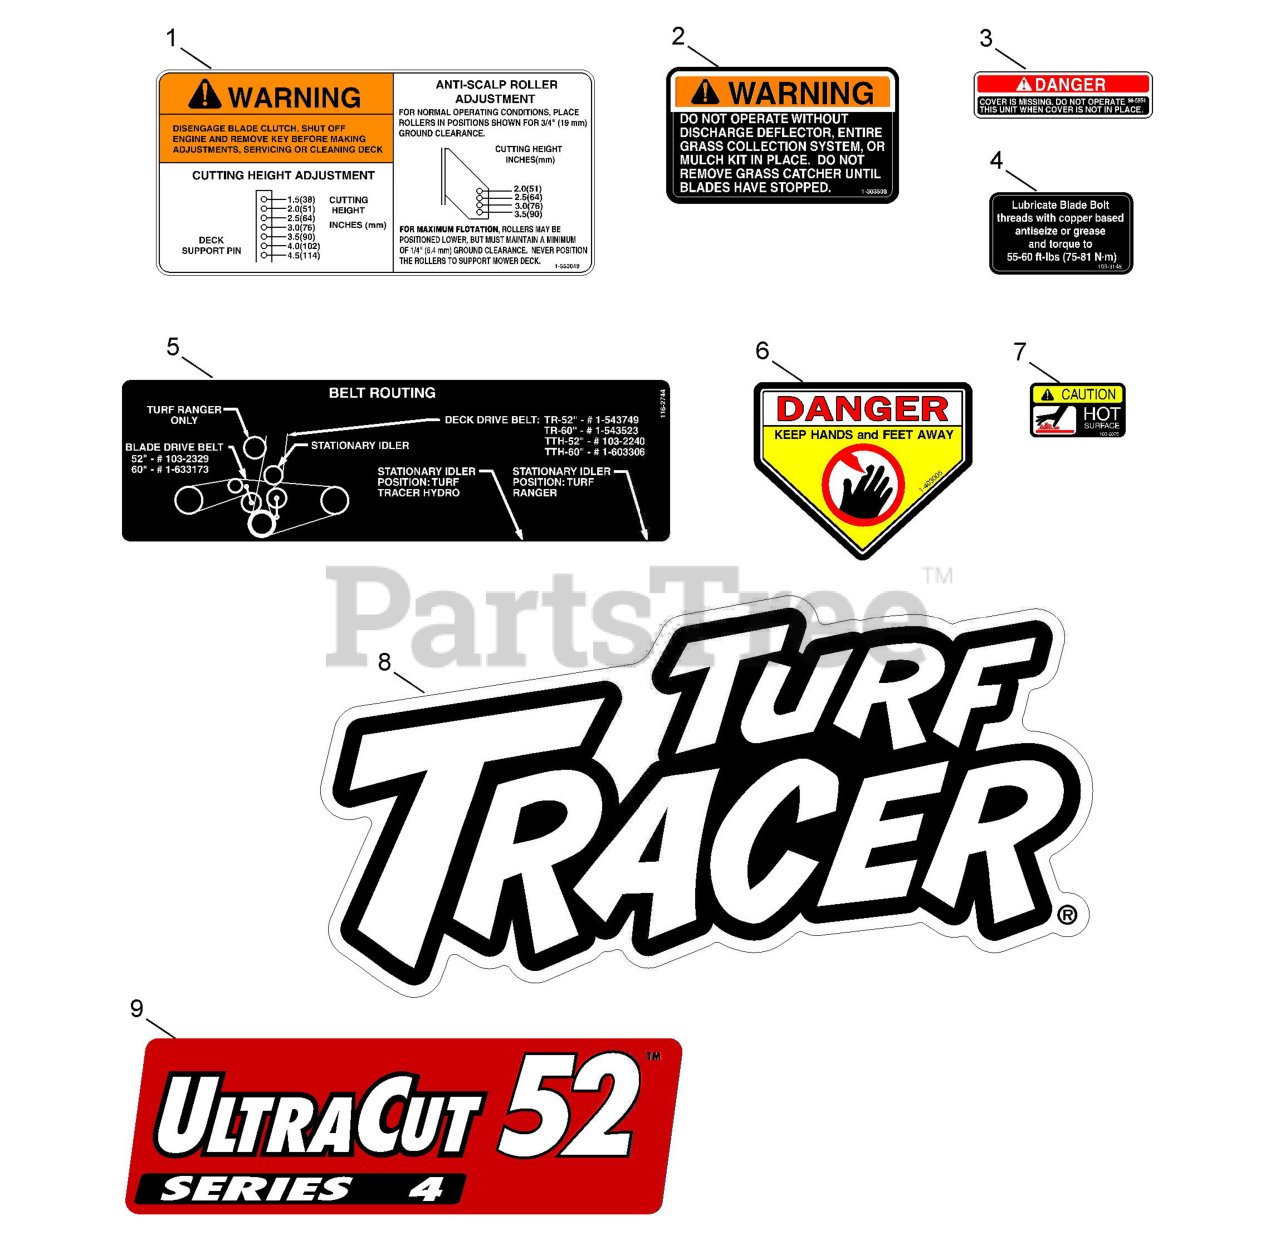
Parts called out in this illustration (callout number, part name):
1	DECAL,ANTI SCALP
2	DECAL-WARNING, DISCHARGE
3	DECAL-COVER, MISSING
4	DECAL,BOLT TORQUE
5	DECAL-BELT ROUTING
6	DECAL-DANGER
7	DECAL-CAUTION
8	DECAL,TTH MODEL
9	DECAL,ULTRACUT 52 SERIES
